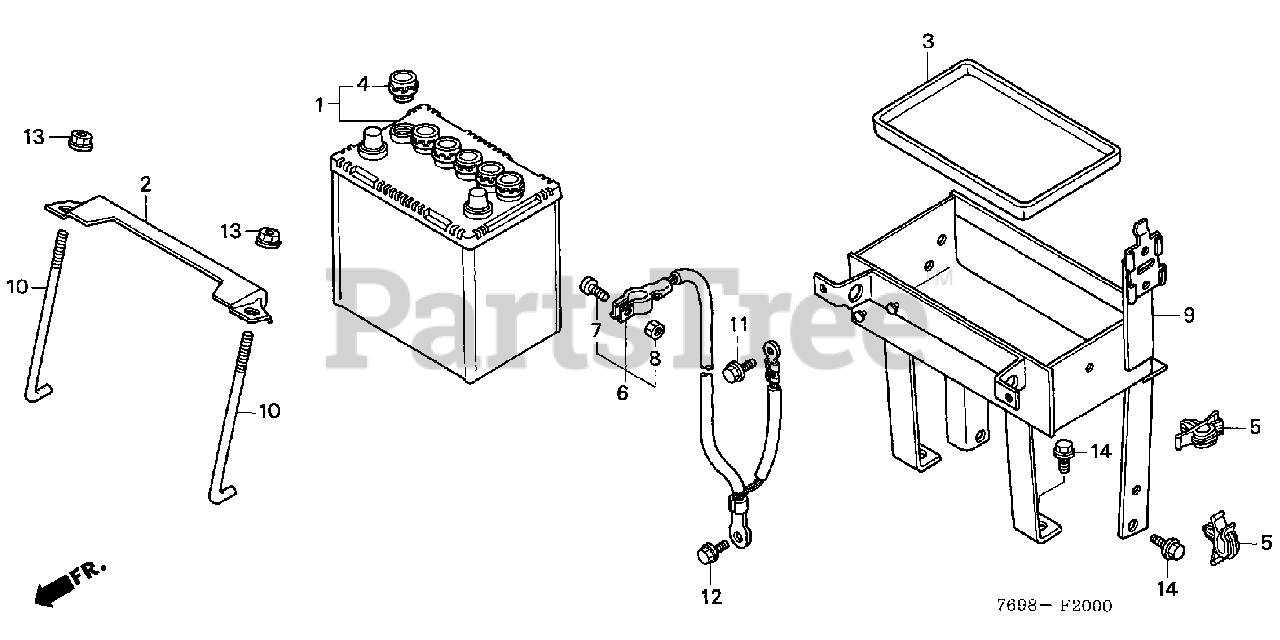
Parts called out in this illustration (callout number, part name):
1	BATTERY ASSY. (32A19RT-S) (YUASA)
2	PLATE, BATTERY SET
3	BOX, BATTERY
4	PLUG, VENT (YUASA)
5	CLIP, WIRE HARNESS
6	CABLE ASSY., GROUND
7	BOLT, BATTERY TERMINAL (SUMITOMO)
8	NUT, BATTERY TERMINAL (SUMITOMO)
9	HOLDER, BATTERY
10	BOLT, BATTERY SETTING
11	BOLT, FLANGE (6X14)
12	BOLT, GROUND (6X16) (SN)
13	NUT, FLANGE (6MM)
14	BOLT, FLANGE (10X22)
